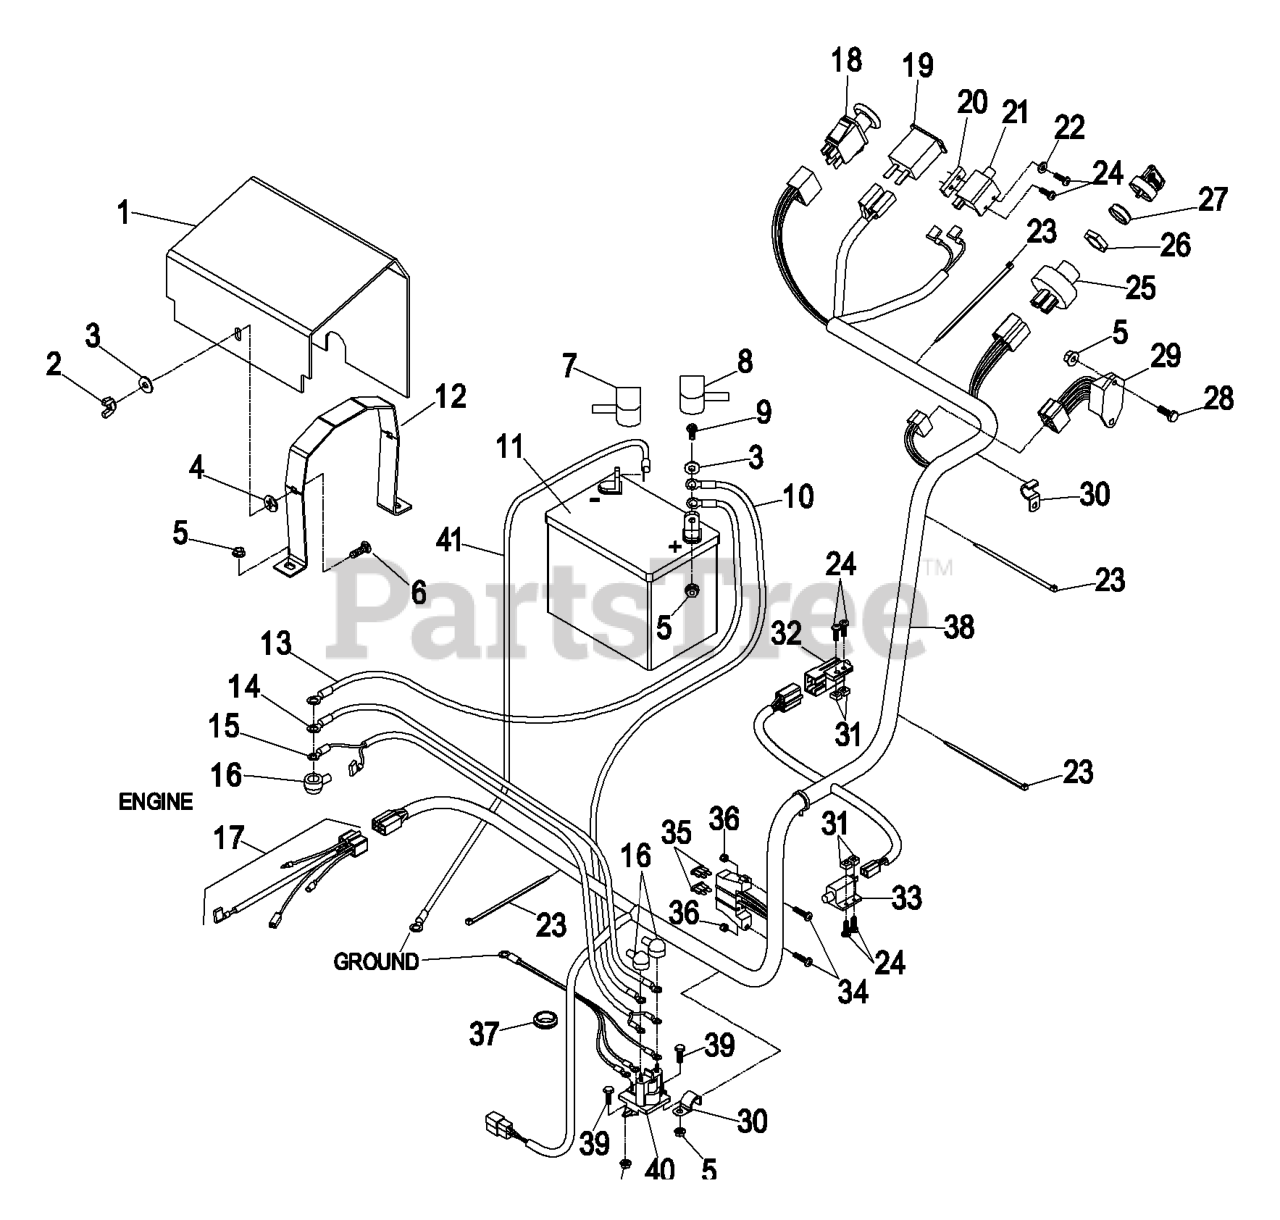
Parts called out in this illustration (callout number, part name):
2	NUT-WING
3	WASHER-FLAT
4	NUT-RETAINING
6	BOLT-CARR
7	INSULATOR, BATTERY -
9	SCREW-HH
12	STRAP,BATTERY HOLDDOWN
16	INSULATOR-SOLENOID
17	HARNESS,WIRING 19KA
19	METER-HOUR
20	PLATE-TAPPED
21	SWITCH-OPEN, NORMALLY
22	WASHER-FLAT
23	TIE-PLASTIC
24	SCREW-PPH
25	SWITCH,IGNITION
26	NUT-SWITCH, IGNITION
27	SEAL-SWITCH, IGNITION
28	SCREW-HH
29	MODULE-OPC NO TIME DELAY
30	CLIP-HALF, LOOM
31	NUT-SQH
33	SWITCH-CLOSED, NORMALLY
34	SCREW-HEAD, TRUSS
35	FUSE-BLADE TYPE, 20 AMP
36	NUT-LOCK, NI
37	GROMMET
39	SCREW-HH
41	WIRE-GROUND
